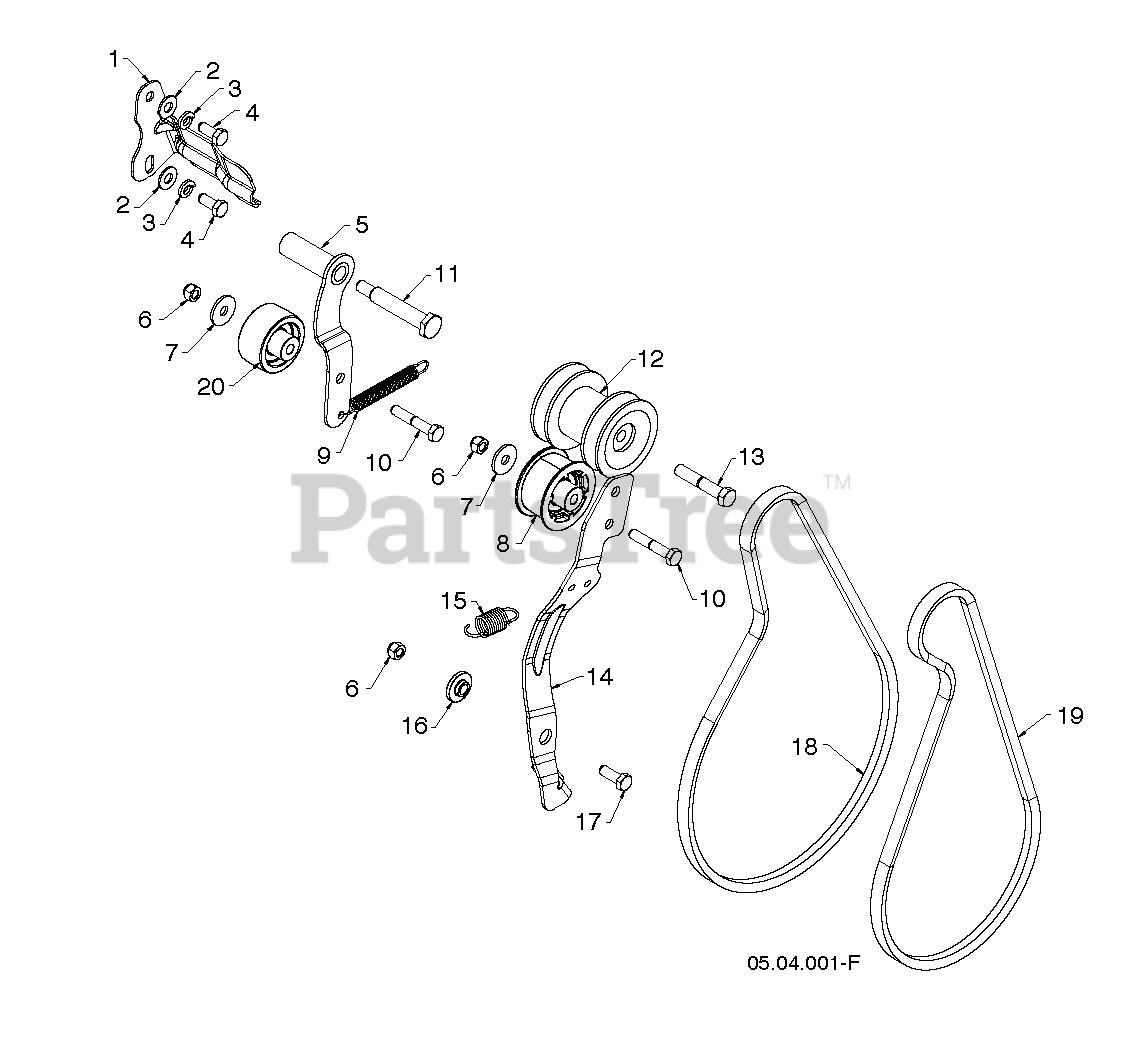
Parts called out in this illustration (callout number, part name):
1	BRACKET.BELT.KEEPER.004.BZP
2	WASHER M
3	LOCKWASHER
4	SCREW 5/16-24 X .75 GR5
5	Drive Weldment Idler Arm, Hot 008
6	NUT.71038.31-18.HEX.NYLOCK
7	STEEL WASHER
8	Idler Pulley, 2.00 W Spa
9	Idler Arm Return Spring
10	BOLT, HEX 5/16-18X1-3/4
11	Hex Head Shoulder Bolt, 5/16-24 X 2.25
13	BOLT.BLADE
14	Impeller Idler Arm Bracket
15	Impeller Idler Arm Return Spring
16	Idler Pivot Bushing
18	Belt, 4L X 38.19
19	Low Crank Impeller Belt
20	Flange Idler Pulley, 2 O/Spacer
